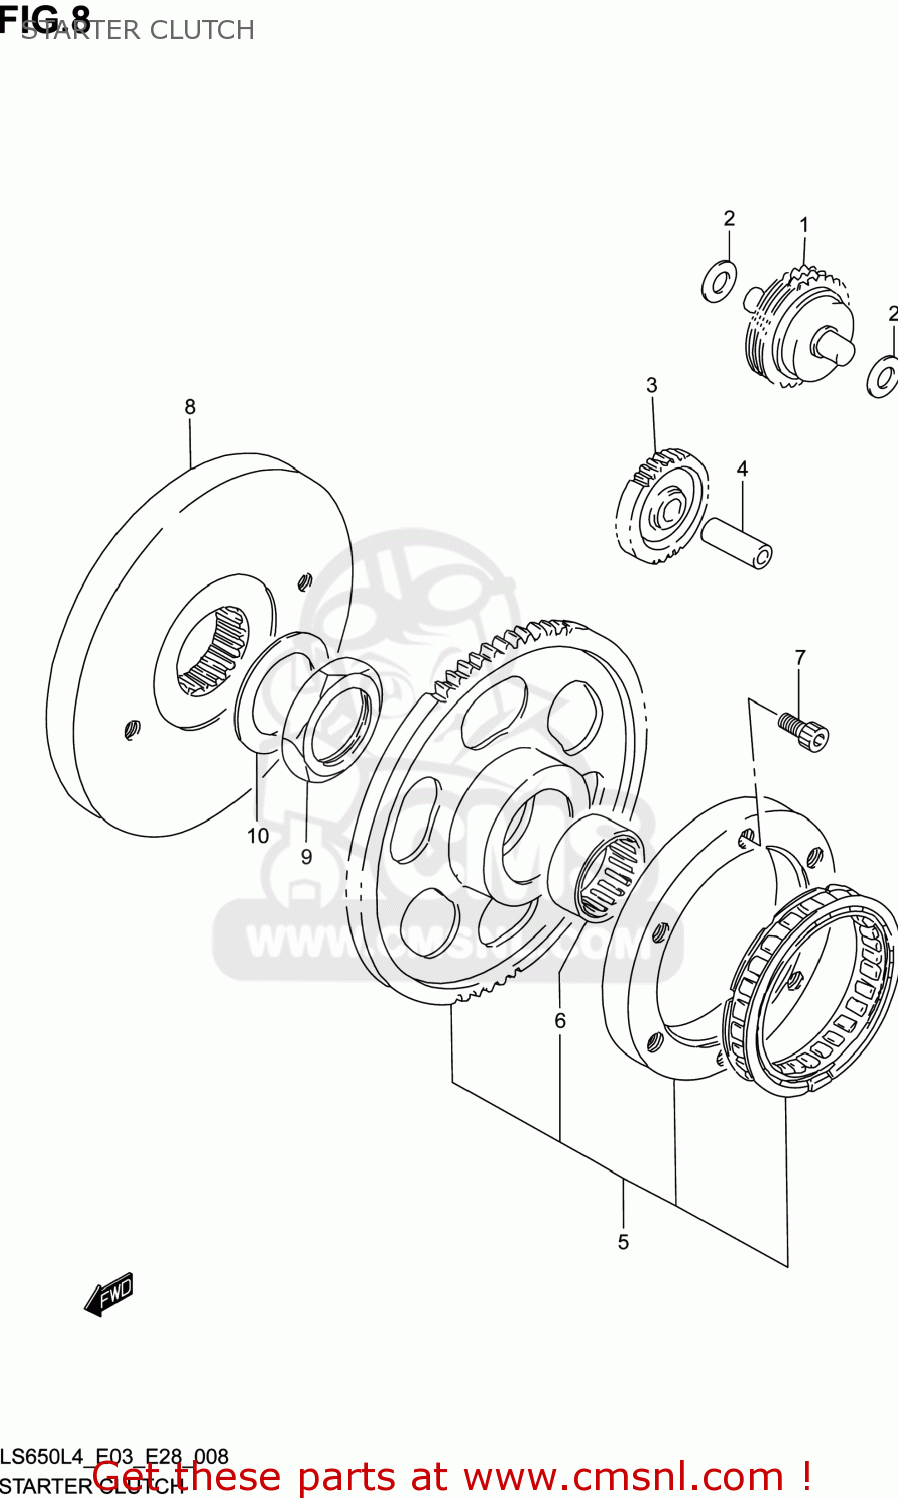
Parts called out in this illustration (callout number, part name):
1	LIMITER ASSY,START ID GR NO.1
2	SHIM(10X18X1)
3	GEAR,STARTER IDLE NO.2
4	PIN(10X30)
5	CLUTCH SET,STARTER
6	BEARING(31X39X17.8)
7	BOLT(8X16)
8	FLYWHEEL
9	NUT,FLYWHEEL
10	WASHER
